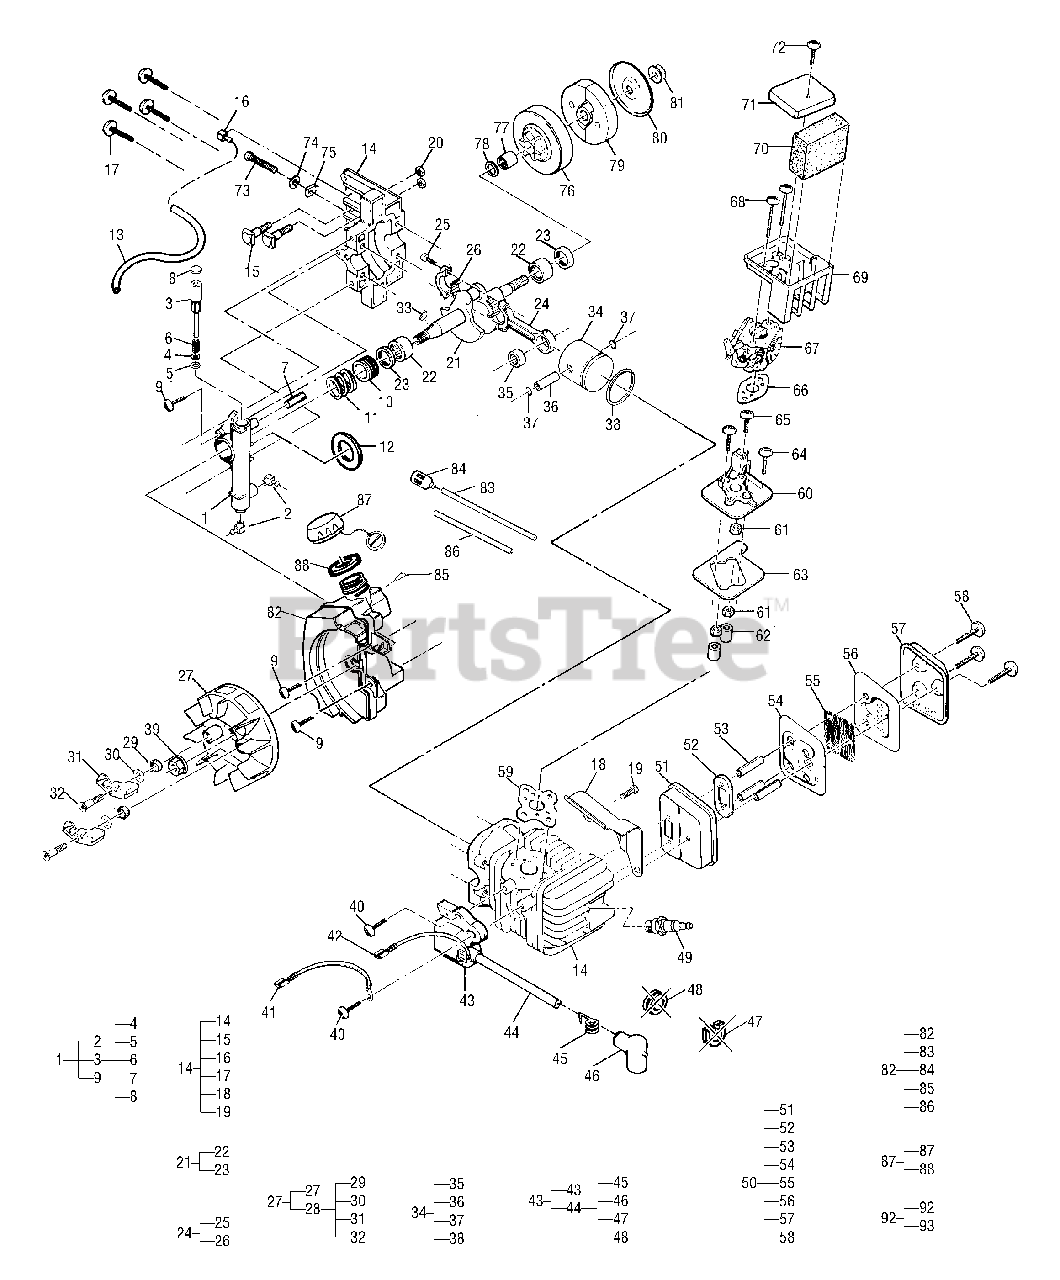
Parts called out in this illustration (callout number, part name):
1	Oil Pump Asy
3	Kit, Gear/Plunger Asy
4	Washer
5	O-Ring
6	Spring
7	Pin, Dowel
8	Plug, Oil Pump
9	Screw, 10-24 x .62 Tr Hd Torx
10	Worm Gear
11	Spring, Compression
12	Seal, Foam, Oil Pump
13	Connecting Hose
14	Short Block Asy
15	Bolt, Bar
16	Fitting
17	Screw, 12-24 x 1.0 Hx Wshr Hd
18	Baffle, Air
19	Screw, 10-24x.625
20	Nut, Hx 1/4-28 Flange
21	Crankshaft/Bearing Asy
22	Bearing, C'shaft
23	Seal, C'shaft Oil
24	Connecting Rod/Bearing Asy
25	Screw, Conn Rod
26	Set, Roller Pins
27	Flywheel/Pawl Asy
28	Kit, Flywheel Pawls
29	Spring, Starter Pawl
30	Washer, Sp .469 OD x .222 ID
31	Pawls
32	Pin, Starter Pawl
33	Key, Flywheel
35	Bearing, Needle- Drawn Cup
36	Pin, Piston
37	Ring, Snap
39	Nut, Hx 5/16-24
40	Screw, Tr 10-24 x .75 Torx
41	Wire Asy, Ground
42	Wire Asy, Stop Switch
43	Ignition Asy
44	Kit, Plug Wire
45	Connector
47	Grommet
48	Grommet
49	Spark Plug RDJ7Y
50	Muffler Asy
51	Body
52	Plate, Reinforcing
53	Spacer
54	Baffle, Inner Muffler
55	Screen, Spark Arrester
56	Baffle, Outer
57	Cover, Muffler
58	Screw, 10-24 x 1.75 Tr Hd Torx
59	Gasket, Insulator
60	Insulator, Carburetor
61	Nut, Hx 10-24
62	Spacer, Rubber
63	Seal, Foam
64	Screw, Tr 10-24 x 1.00 Torx
65	Screw, Tr 10-24 x .75 Torx
66	Gasket, Carburetor
67	Carburetor/Choke Asy
68	Screw, Tr 10-24 x 2.0 Torx
69	Box, Air Filter
70	Filter, Air
71	Shield, Carburetor
72	Screw, 10-14 x .625 Plastite
73	Gas Bar Adj Screw Nut & Ring
74	Ring, Retaining
75	Nut, Bar Adjusting
76	Drum/Sprocket/Bearing Asy
77	Bearing
78	Washer, Sprocket
79	Kit, Clutch Asy
80	Plate, Dust
81	Nut, Clutch, 5/16-24 LH
82	Fuel Tank Asy
83	Hose, Fuel Pickup
84	Filter, Fuel
85	Valve, Duckbill
86	Hose, Primer Retain
87	Cap, Fuel Asr
88	Gasket, Fuel Cap
